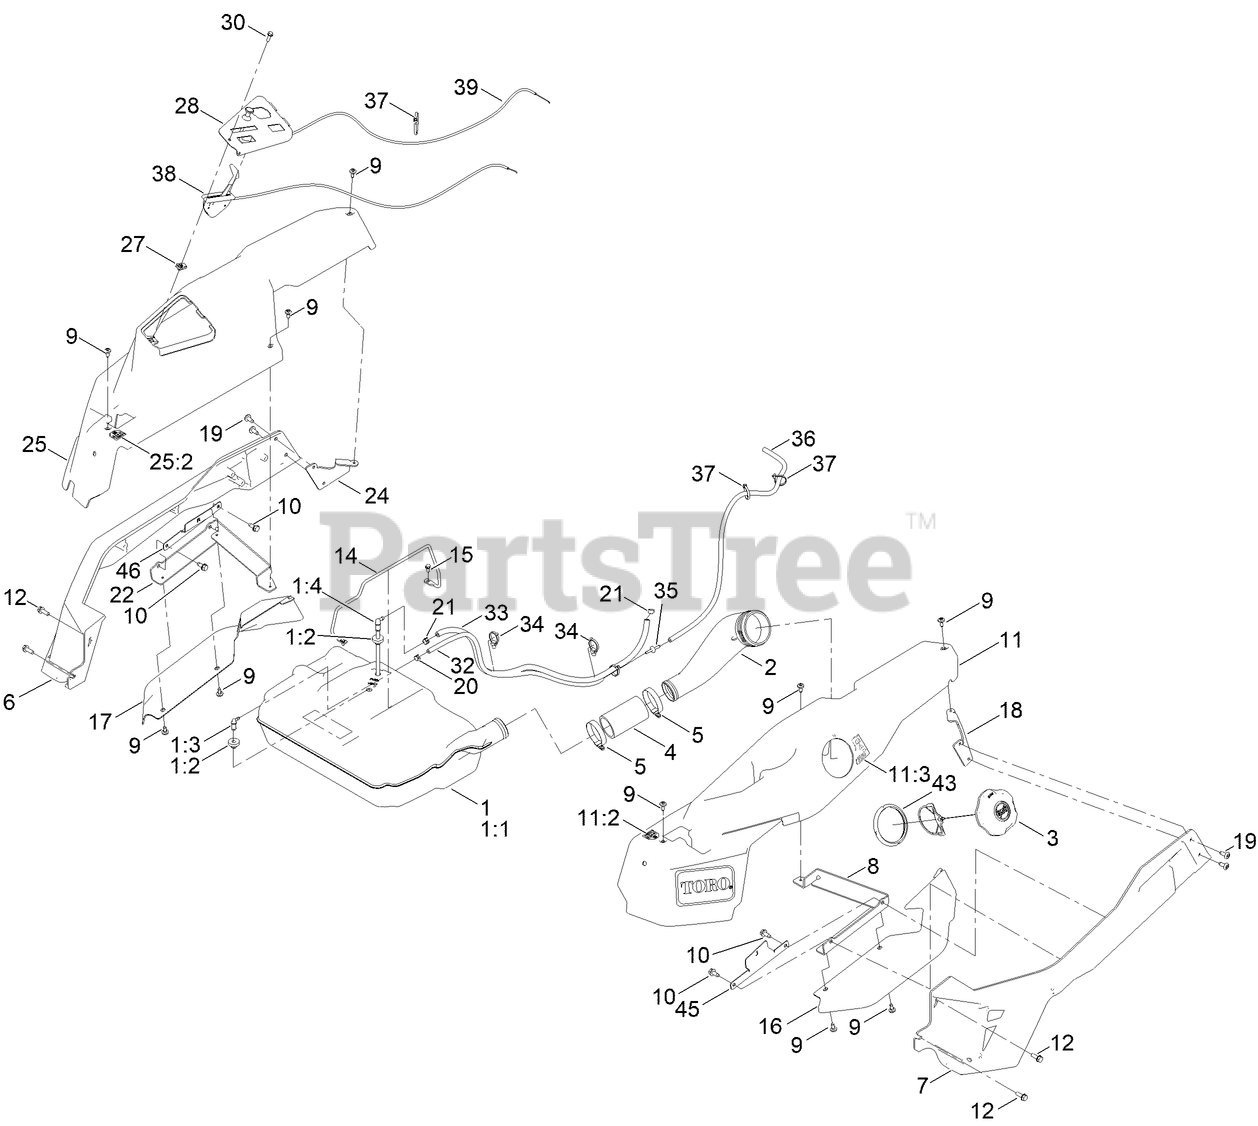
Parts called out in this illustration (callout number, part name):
1	FUEL TANK ASM
1:1	TANK-FUEL
1:2	BUSHING
1:3	FITTING-ELBOW 90
1:4	FITTING - PICKUP, FUEL
2	NECK-FILLER, FUEL
3	CAP-FUEL, RATCHETING
4	HOSE-FILLER, FUEL
5	CLAMP-HOSE
6	CAST-TUBE, RH [BLK-TXT]
7	CAST-TUBE, LH [BLK-TXT]
8	MOUNT-POD BRACKET LH
9	SCREW-SHOULDER
10	SCREW-HWHTF
11	POD ASM - LH W/DECALS
11:2	DECAL-CONTROL LEVER, LH
11:3	DECAL-FUEL FILL
12	SCREW-TAPTITE
14	ROD-HOLD DOWN
15	SCREW-HWH
16	FENDER-TIME CUTTER, LH
17	FENDER-TIME CUTTER, RH
18	BRACKET-REAR POD, LH
20	CLAMP-HOSE
21	CLAMP-HOSE
22	MOUNT-POD BRACKET RH
24	MOUNT-POD BRACKET RH
25	POD ASM - RH W/DECALS
25:2	DECAL-CONTROL LEVER, RH
28	PANEL-CONTROL
30	SCREW-HWH
32	HOSE-FUEL
33	HOSE-FUEL
34	CLIP-TIE
35	ADAPTER ORIFICE
36	HOSE-LP
37	TIE-CABLE
38	CABLE-THROTTLE
39	CABLE-CHOKE
43	RING-RETAINING
45	BRACKET-ALIGNMENT, POD LH
46	BRACKET- ALIGNMENT, POD RH
